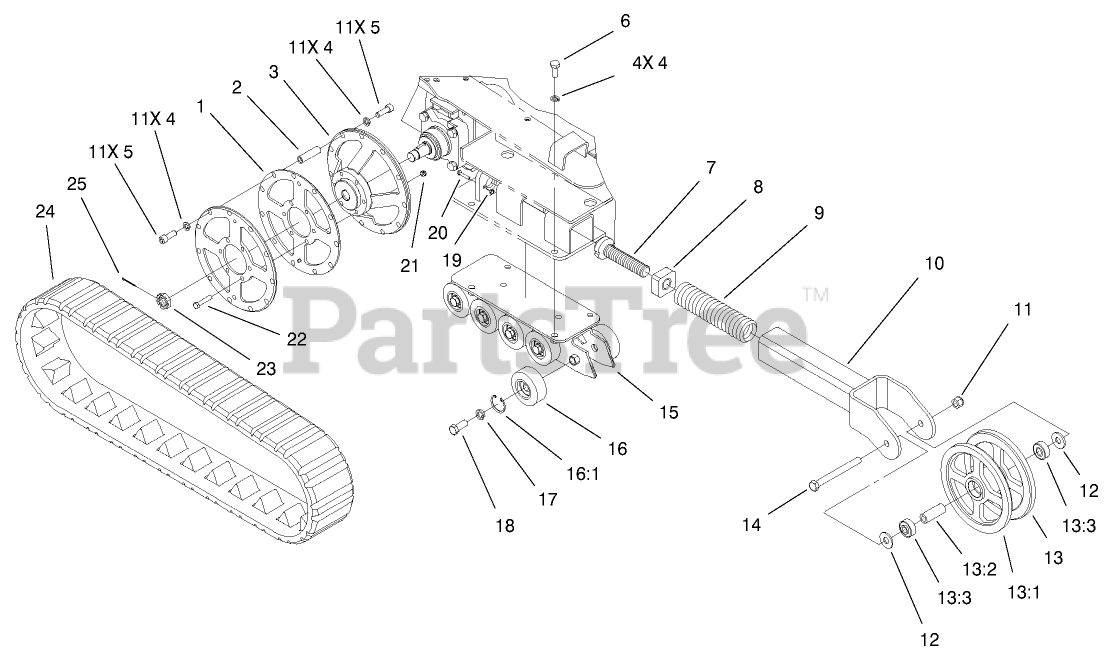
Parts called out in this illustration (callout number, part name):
1	PLATE-WHEEL, DRIVE
2	SPACER-WHEEL, DRIVE
3	DRIVE WHEEL ASM
4	WASHER-LOCK
5	SCREW-HSH
6	SCREW-HH
7	BOLT-TENSIONER
8	BLOCK-TENSIONER
9	SPRING-COMPRESSION
10	TENSIONER ARM ASM
11	NUT-HEX
12	WASHER-FLAT
13	TENSIONER WHEEL ASM
13:1	TENSIONER WHEEL ASM
13:2	SPACER-WHEEL, TENSIONER
13:3	BEARING
14	SCREW-HH
15	Track Guide ASM
16	BOGGY WHEEL ASM
16:1	RING-RETAINING
17	WASHER-LOCK
18	SCREW-HH
19	NUT-LOCK, NI
20	SCREW-HH
21	NUT-LOCK, SIDE
22	SCREW-HH
24	TRACK
25	PIN-COTTER
